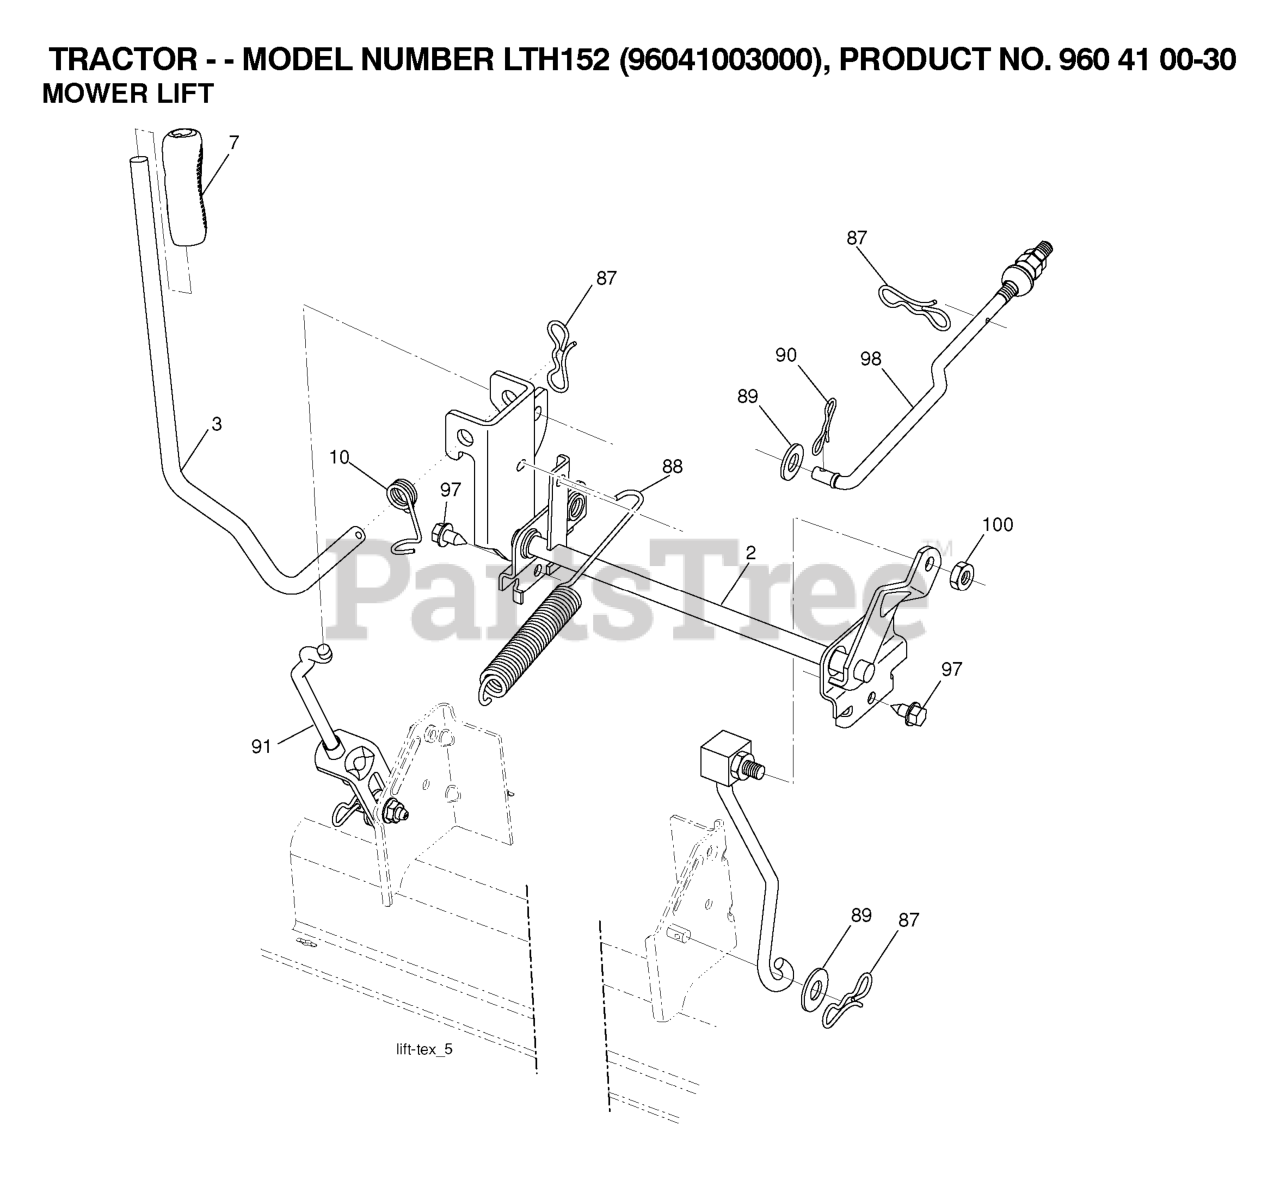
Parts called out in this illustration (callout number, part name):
2	SHAFT.ASM.LIFT.CROSS.H
3	LEVER.LIFT.HANDLE.LT
7	GRIP.HANDLE.LIFT.PVC.BLACK
10	SPRING.TORSION.LIFT.HANDLE
87	PIN.COTTER.7/16.BOW TI.
88	SPRING.LIFT.ASSIST.LT
89	WASHER.CLEAR.ZINC
90	PIN.COTTER.5/16.BOW TI
91	LINK.ASM.LIFT.REAR
97	SCREW 3/8-16X3/4
98	LINK.ASM.SUSP.FRONT.MW
100	LOCKNUT
